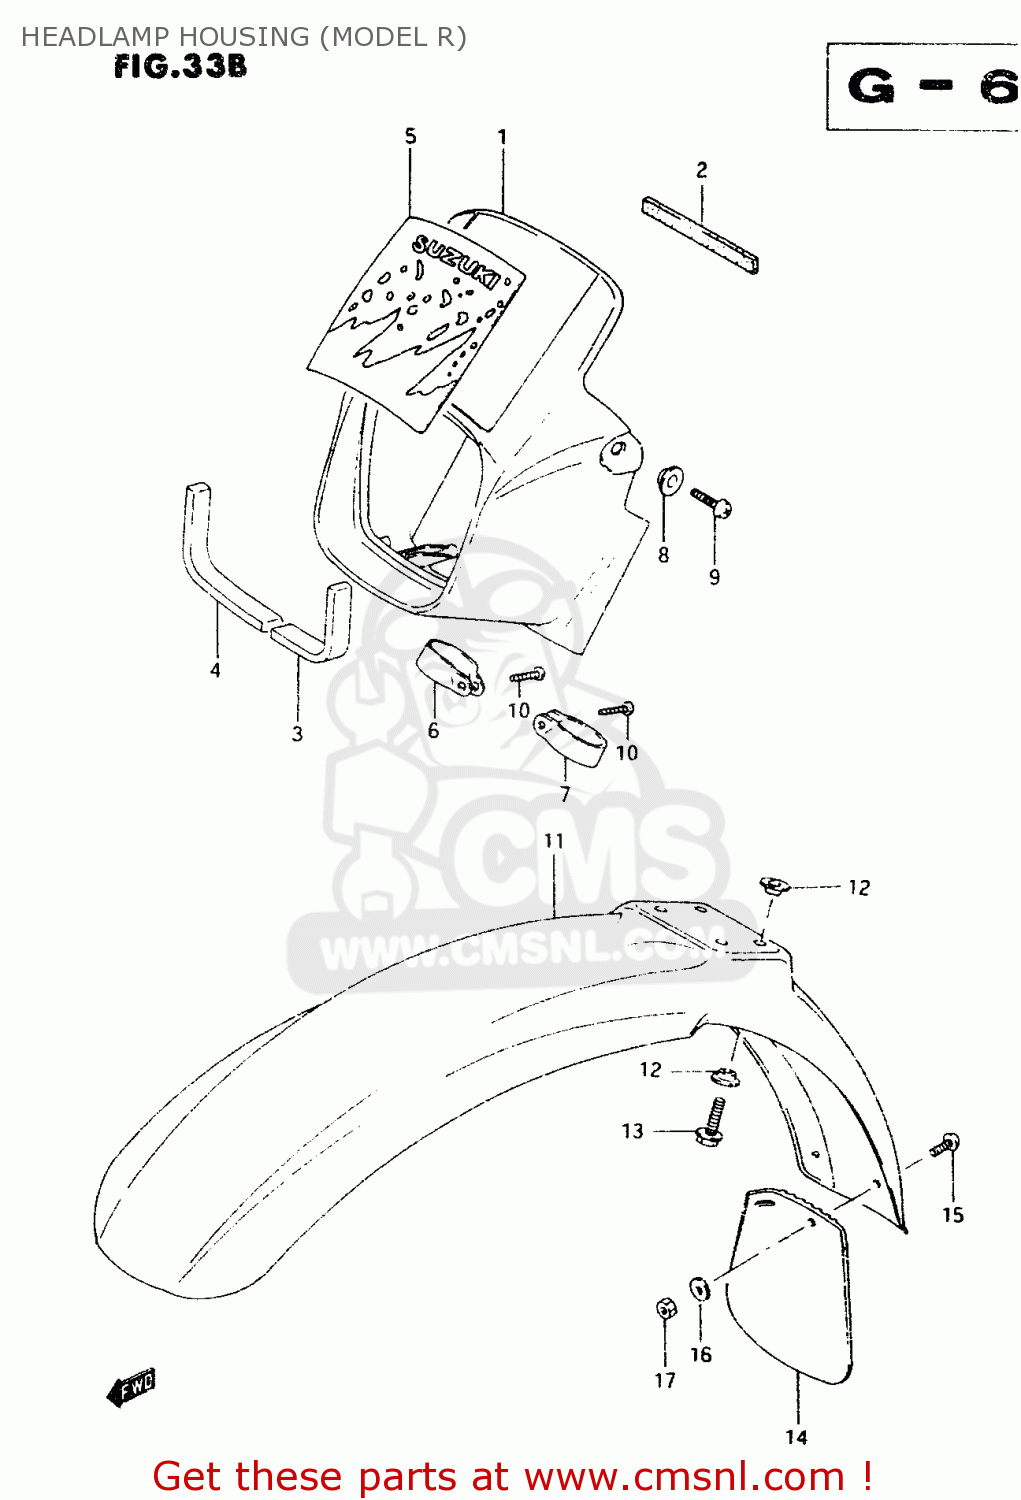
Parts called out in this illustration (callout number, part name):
1	HOUSING, HEADLAMP (BLUE)
2	CUSHION,HEADLAMP HOUSING
3	CUSHION,HEADL.
4	CUSHION,HEAD L
5	TAPE, HEADLAMP COVER
6	CLAMP,HEADLAMP HOUSING,R
7	CLAMP, HEADLAMP HOUSING, LH
8	WASHER
9	SCREW
10	SCREW
11	FENDER,FR
12	WASHER
13	BOLT
14	GUARD,MUD
15	SCREW 5X12
16	WASHER
17	NUT
